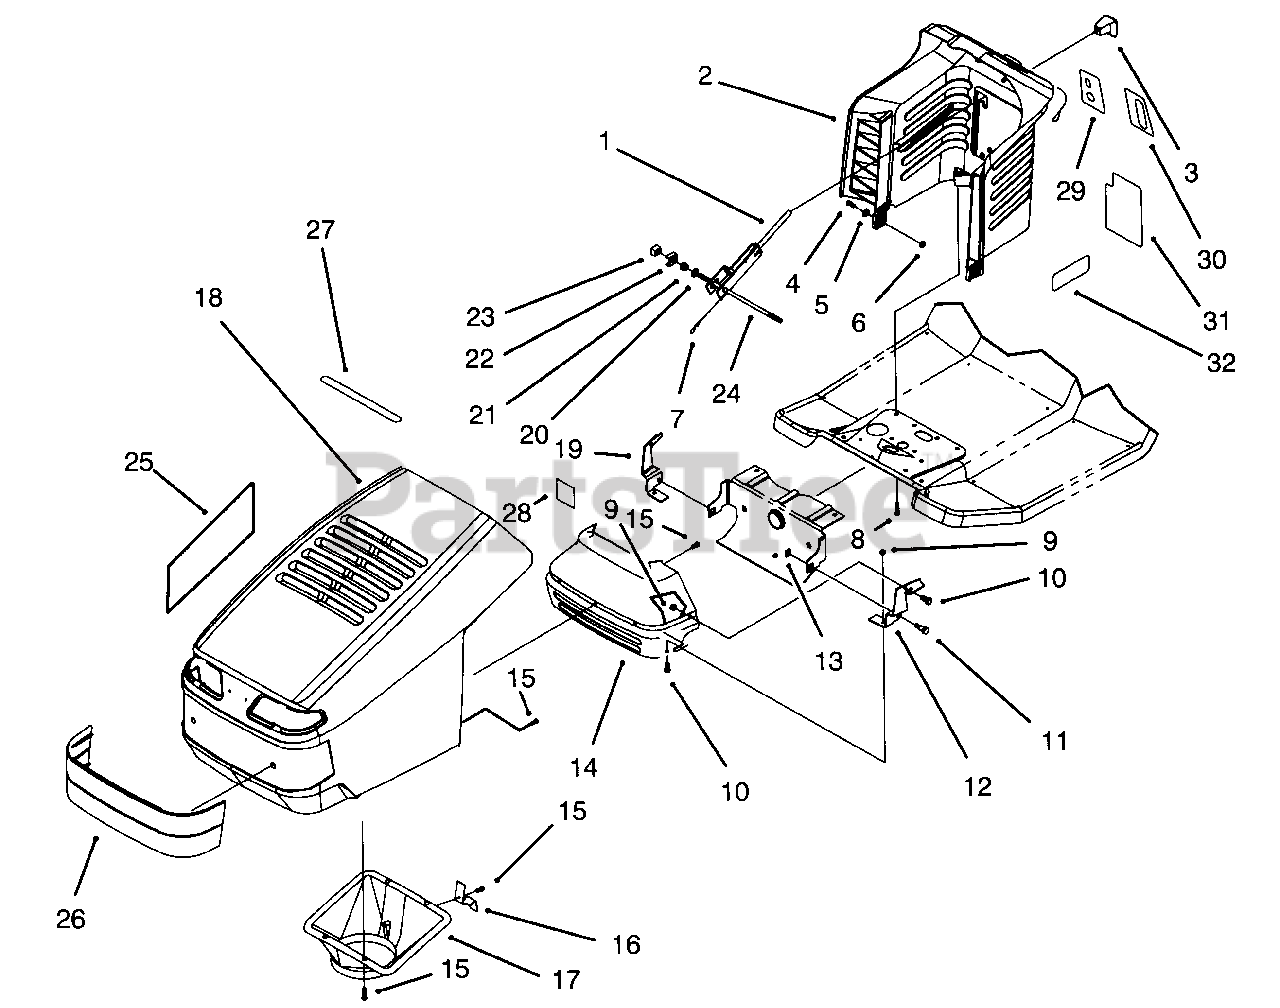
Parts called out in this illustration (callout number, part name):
1	Lever-Deck Engage
2	Tower-Steering
3	Knob-Engage Lever
4	Screw-Hex Hd. Cap
5	Washer-Flat
6	Nut-Lock
7	Pin-Cotter
8	Screw-Plastite
9	Nut-Lock
10	Screw-Hex Hd. Cap
11	Bolt-Shoulder
12	Bracket-Hood Pivot L.H.
13	Nut-Retained
14	Shield-Heat
15	Screw-Plastite
16	Latch-Hood
17	Duct-Hood Air
18	Hood
19	Bracket-Hood Pivot R.H.
20	Washer-Flat
21	Nut-Flange
22	Clamp-Pivot Rod
23	Nut-Wedge
24	Rod-Tower Pivot
25	Decal-Hood R.H.
26	Panel-Grille
27	Decal-Air Duct
28	Patch-Heat Tape
29	Decal-Ignition/Lights (Model No. 81180 & 81191 Only)
30	Decal-Throttle
31	Decal-Deck Engage
32	Decal-Tower LT-12G (Model No. 81182 Only)
